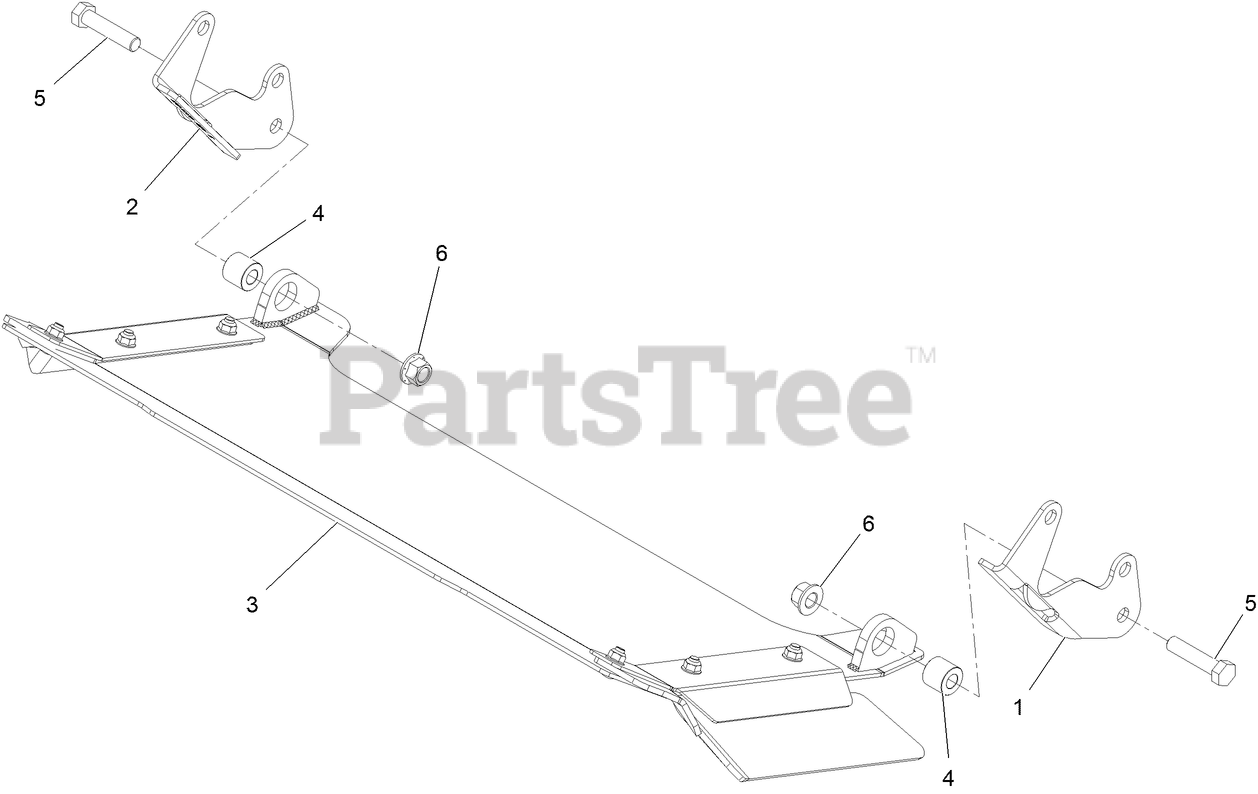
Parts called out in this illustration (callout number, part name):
1	BRACKET-DISCHARGE MOUNT, LH
2	BRACKET-DISCHARGE MOUNT, RH
3	DISCHARGE TUNNEL ASM
4	BUSHING-SLEEVE
5	SCREW-HH
6	NUT-LOCK
